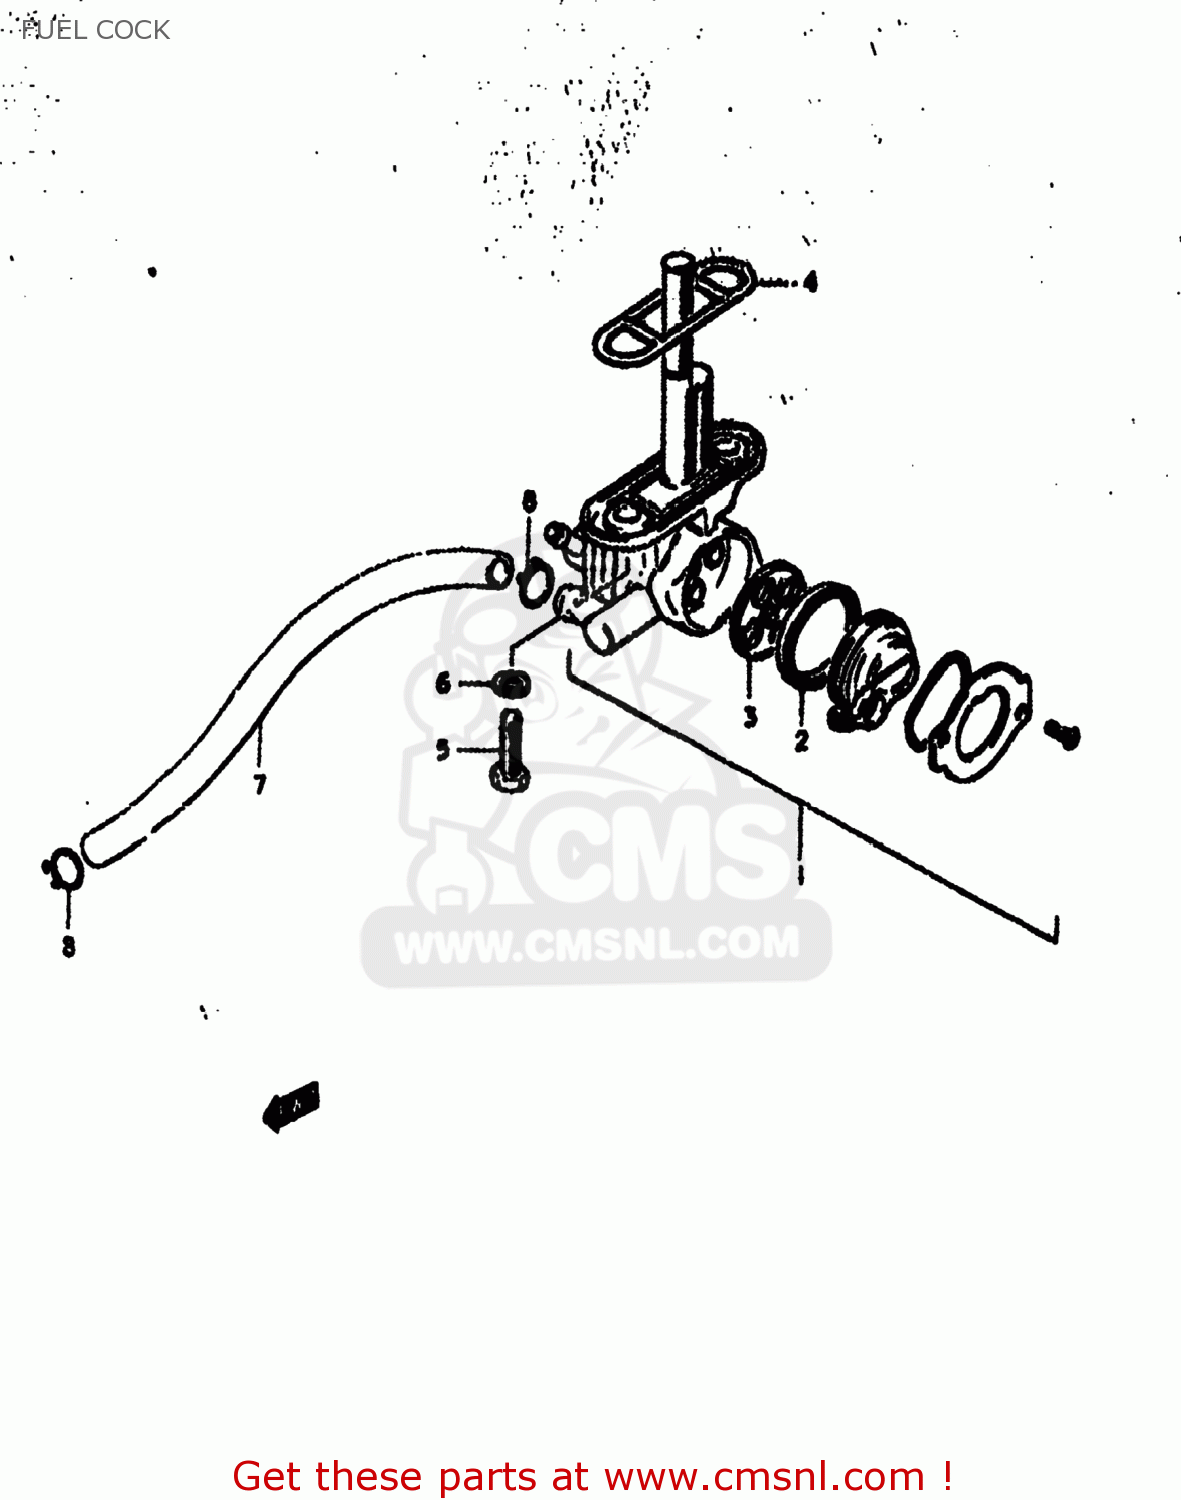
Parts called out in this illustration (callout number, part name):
1	COCK ASSEMBLY,FUEL
2	V SEAL,FUEL COCK
3	GASKET (NAS)
4	GASKET,FUEL COCK (NAS)
5	BOLT(6X20)
6	GASKET
7	HOSE
8	CLIP
